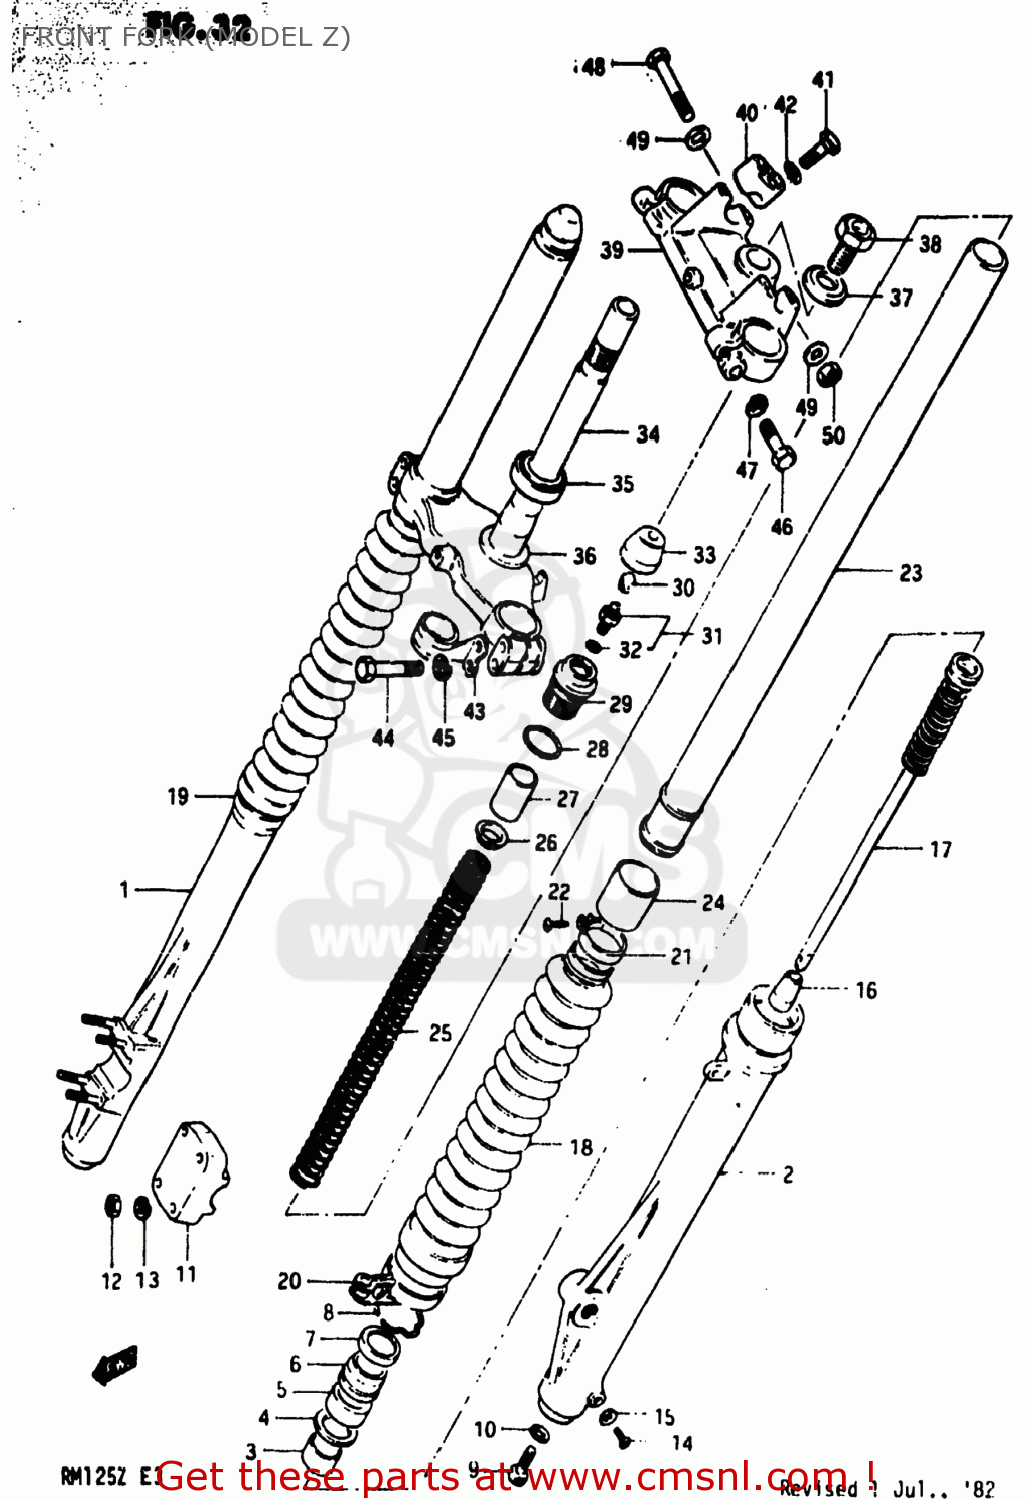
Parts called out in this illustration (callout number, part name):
1	TUBE,OUTER,RIGHT
2	TUBE,OUTER,LEFT
3	METAL,SLIDE
4	WASHER(40X50X2.3)
5	SEAL,OIL
6	SEAL,DUST
7	CASE,DUST SEAL
8	RING,STOPPER
9	BOLT,CYLINDER
10	GASKET,CYLINDER (NAS)
11	HOLDER,AXLE
12	NUT
13	LOCK WASHER
14	SCREW
15	GASKET,DRAIN,PLUG (NAS)
16	PIECE,OIL LOCK
17	CYLINDER,FRONT FORK
18	BOOT
19	BAND,FRONT FORK COVER BOOT
20	BAND,FRONT FORK COVER BOOT
21	BAND,BOOT
22	SCREW 4X10
23	TUBE,FORK,INNER
24	PISTON
25	SPRING,FRONT FORK
26	GUIDE
27	SPACER,FRONT FORK SPRING
28	O RING
29	CAP,FORK INNER TUBE
30	CAP,VALVE AIR
31	VALVE,FRONT FORK AIR
32	O-RING
33	CAP
34	STEM,STEERING
35	BEARING
36	WASHER,THRUST
37	WASHER
38	BOLT
39	HEAD,STEERING STEM
40	HOLDER,HANDLEBAR
41	BOLT
42	LOCK WASHER
43	CLIP,CABLE
44	BOLT 8X45
45	LOCK WASHER
46	BOLT
47	LOCK WASHER
48	BOLT 8X50
49	WASHER
50	NUT
